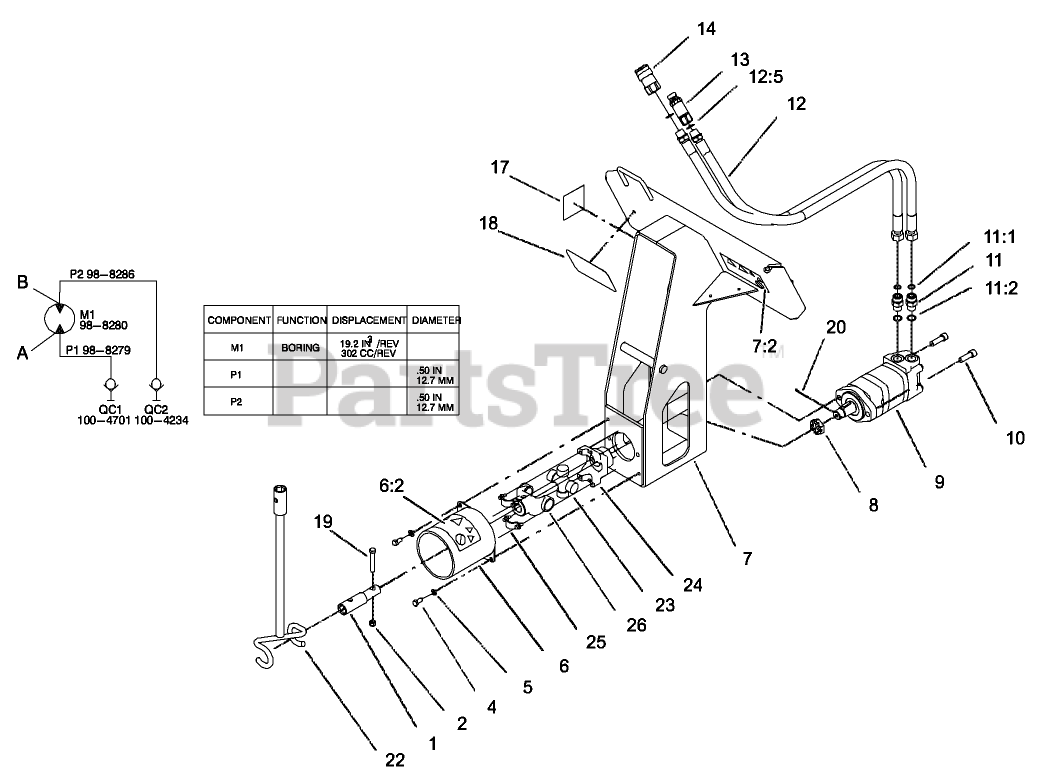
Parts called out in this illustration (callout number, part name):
4	SCREW-HH
5	WASHER-LOCK
6	SHIELD ASM
6:2	DECAL-WARNING
7	BORE FRAME ASM
7:2	DECAL-WARNING
9	MOTOR-HYDRAULIC
10	SCREW-HSH
11	FITTING-STRAIGHT
11:1	O-RING
11:2	O-RING
12	HOSE ASM
12:5	O-RING
13	NIPPLE-CONNECT, PRESSURE
17	DECAL
18	DECAL
19	SCREW-HH
20	PIN-COTTER
22	TOOL-GUIDE, ROD
23	U-JOINT
24	YOKE-U-BOLT
25	BEARING STRAP KIT
26	YOKE-UJOINT
